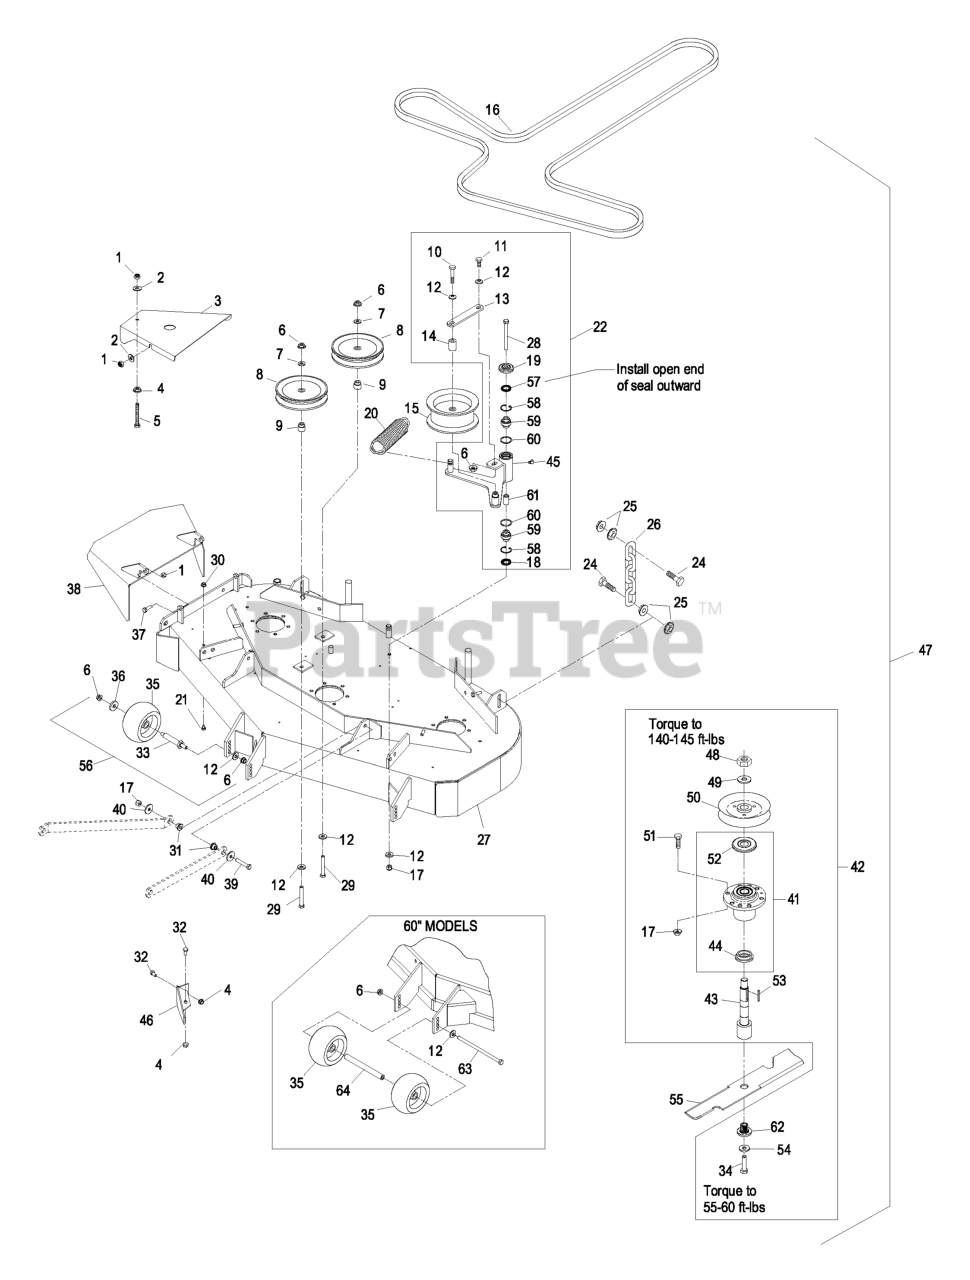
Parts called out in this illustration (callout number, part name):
1	NUT-LOCK, NI
2	WASHER-FLAT
3	SHIELD,BELT
5	BOLT,TAP HH
6	NUT-HHF, WHIZ
7	WASHER-FLAT
8	PULLEY-IDLER
9	BUSHING-IDLER
10	SCREW-HH
11	SCREW-HH
12	WASHER-BELLEVILLE
13	PLATE,GUIDE BELT (PLTD)
16	BELT,BLADE DRIVE
17	NUT-LOCK, NI
18	SEAL-LIP, DOUBLE
19	GUARD-TOP
21	SCREW-HH
22	KIT,DECK IDLER LHP/LCT
23	BUSHING-PIVOT, IDLER
24	SCREW-CAP, HH
26	CHAIN-LIFT, DECK
27	ASM,DECK W/ DECALS LCT52
28	SCREW-HH
29	SCREW-HH
31	SPACER-STRUT
32	SCREW-HH
34	SCREW-HH
37	SCREW-HH
38	WLD,DISCHARGE CHUTE
39	SCREW-HH
41	KIT, CUTTER HOUSING
42	ASM, CUTTER HSG 52
43	KIT, SPLINED SPINDLE 103-
44	SPACER-GUARD, BOTTOM
45	FITTING-GREASE, 90 DEG
46	WLD,BAFFLE DISCHARGE
47	Asm, Deck Complete (52")
48	NUT-HH
50	SHEAVE,6.13 EOD
51	SCREW-HH
52	GUARD-BEARING, TOP
53	KEY-RECTANGLE
54	WASHER-SPRING
57	SEAL-LIP, SINGLE
58	RING-SNAP
59	BEARING-SPHERICAL
62	BUSHING,SPLINED
